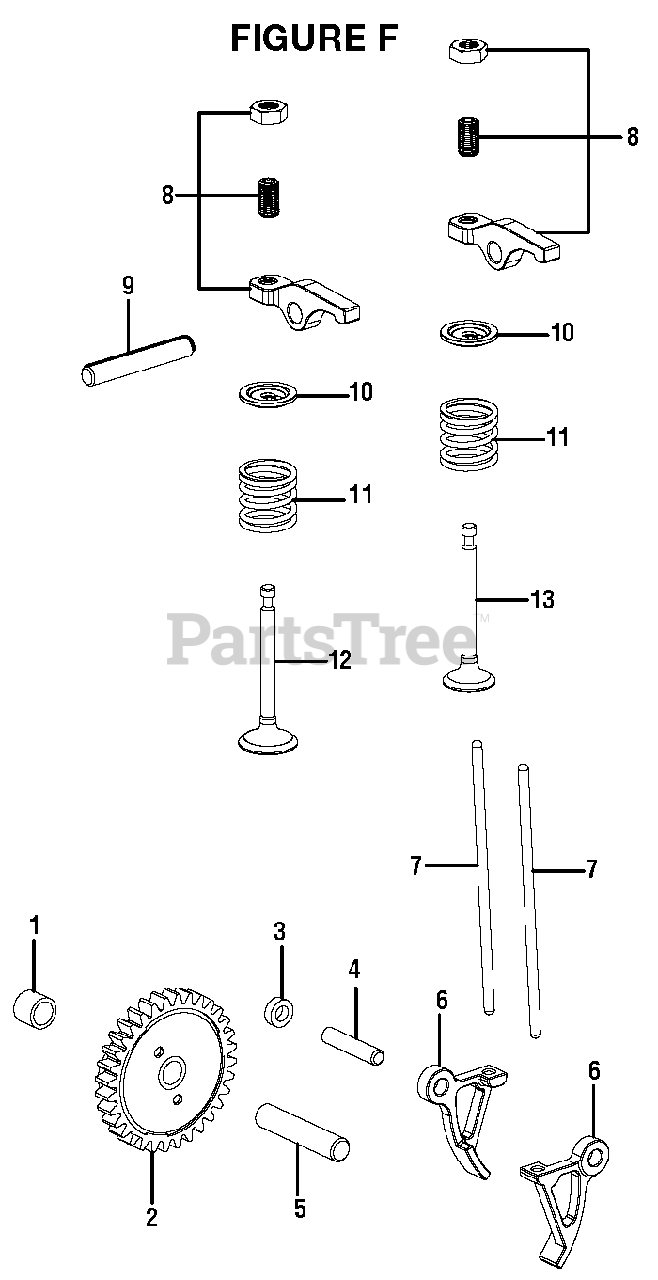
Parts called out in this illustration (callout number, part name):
3	Rocker Gasket
4	Pin (G4 x 20 mm)
5	Pin (G6 x 30 mm)
8	Upper Rocker Assembly
9	Pin (G6 x 32 mm)
10	Valve Spring Seat
13	Exhaust Valve
